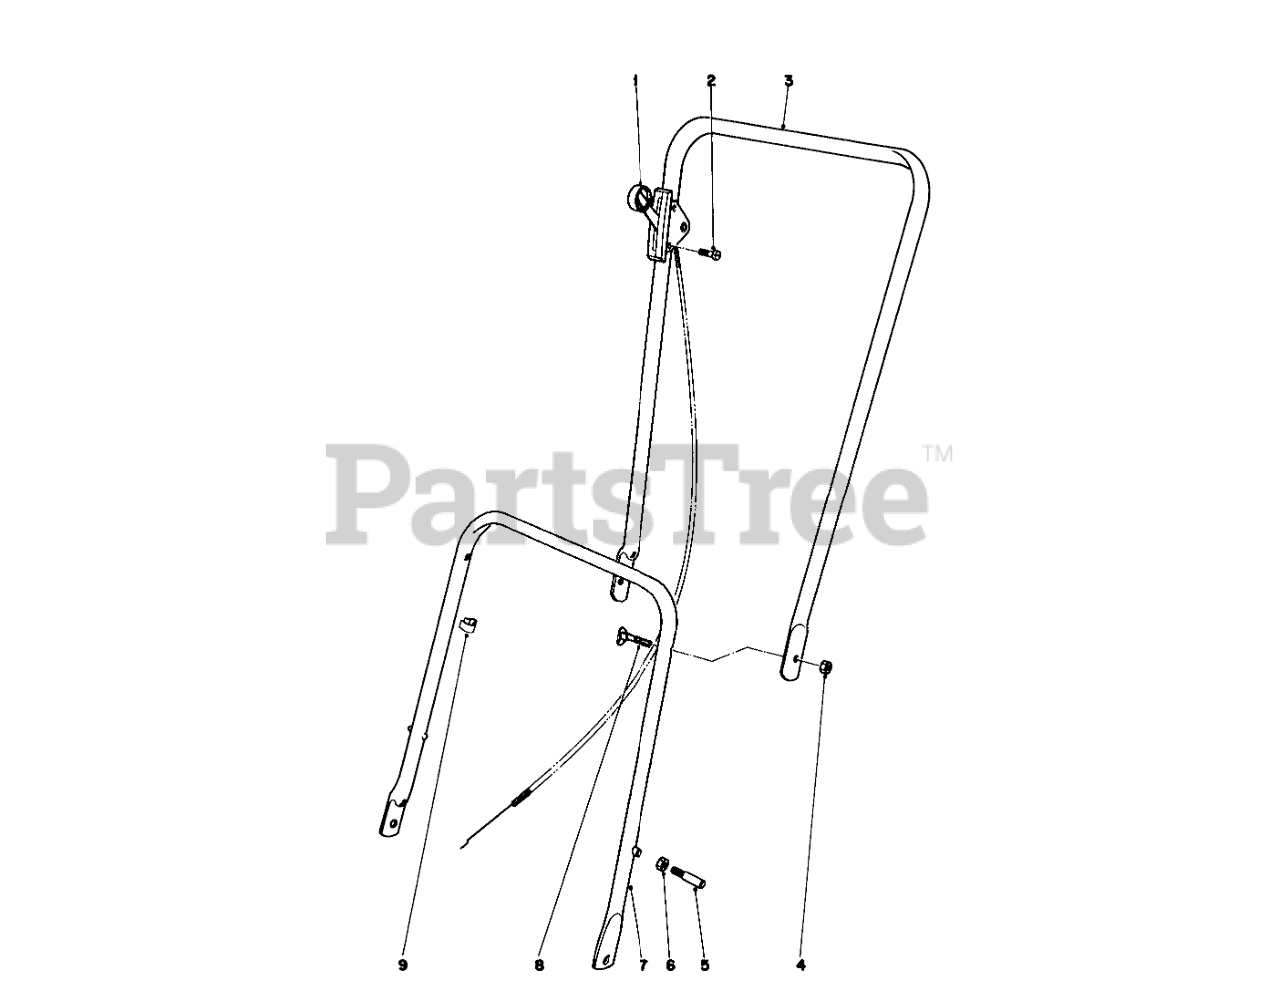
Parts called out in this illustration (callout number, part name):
1	Throttle Control
2	10-24 X 1 PAN HD SCR
3	Handle-Upper
4	Nut
5	HANDLE PIN
6	Nut
7	LWR HANDLE STAKED ASM
8	1-1/4 LG HANDLE SCREW
9	CONTROL WIRE CLIP
